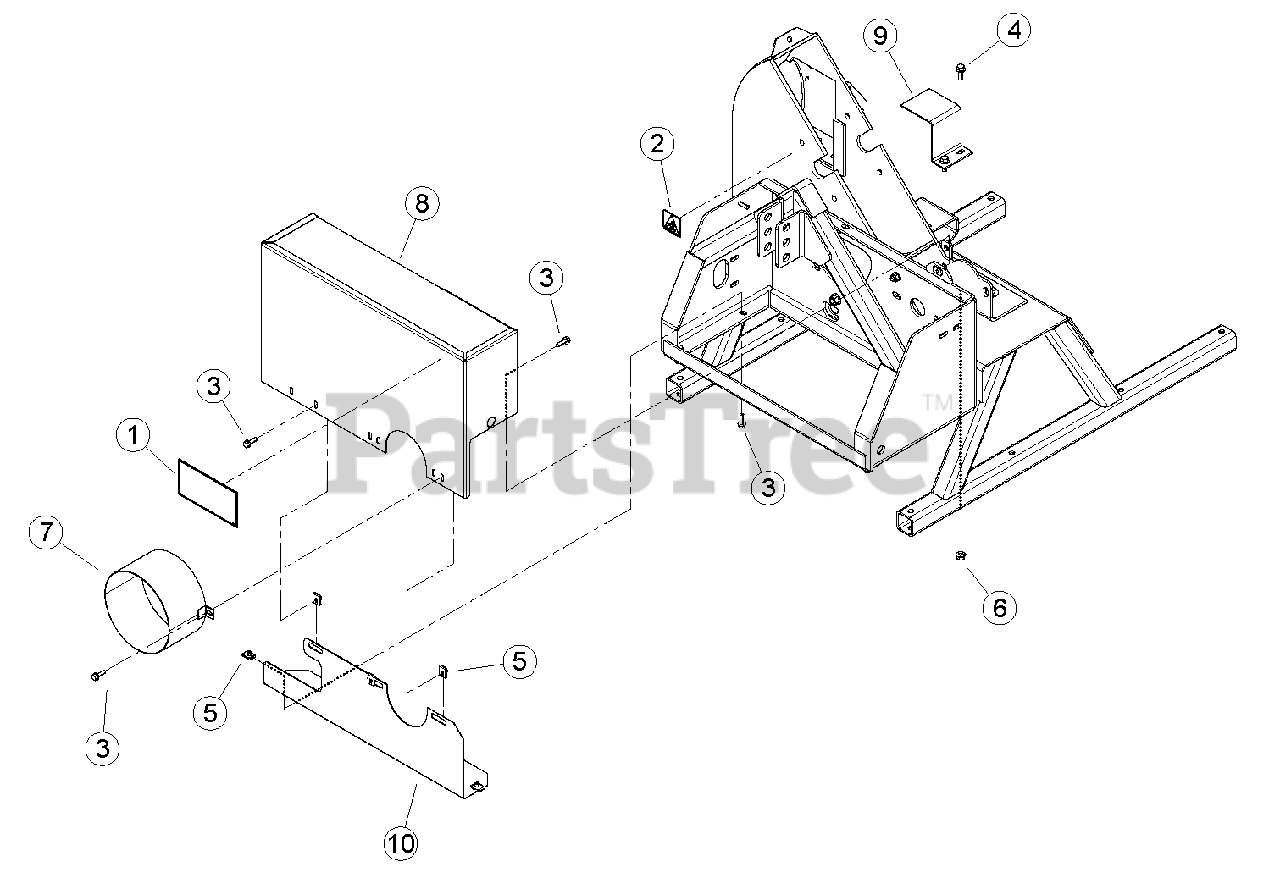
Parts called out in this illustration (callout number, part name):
1	DECAL, PTO DANGER ISO
2	DECAL, SHIELD DANGER ISO
3	BOLT, 5/16 X 1 FLANGE NC
4	BOLT, 3/8 X 1 FLANGE NC
5	NUT, 5/16"-18 TINNERMAN U-TYPE
6	NUT, 3/8-16 NYLOCK FLANGE
7	WELDMENT, PTO SHIELD
8	WELDMENT, UPPER BELT GUARD
9	COVER, JACKSHAFT
10	GUARD, LOWER BELT
